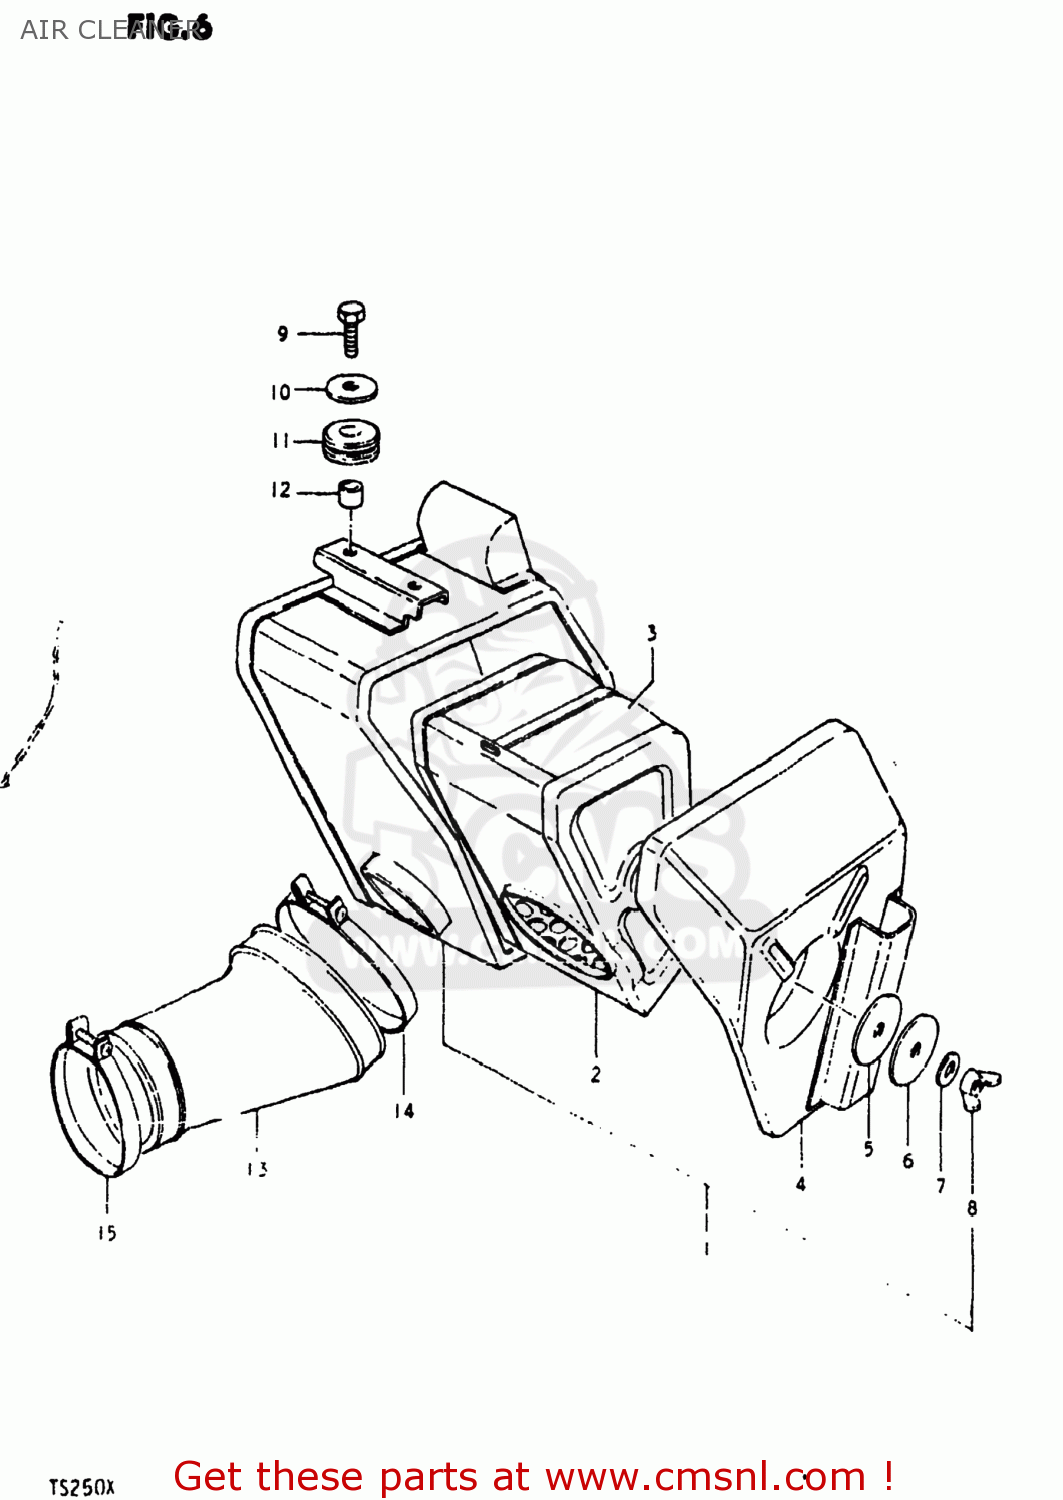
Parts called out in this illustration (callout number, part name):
1	CLEANER ASSEMBLY,AIR
2	FILTER ASSY
3	FILTER
4	CAP,AIR CLEANER
5	SEAL
6	WASHER,AIR CLEANER ELEMENT
7	WASHER
8	NUT
9	BOLT, UPPER
10	WASHER (6.5X20X1.2)
11	CUSHION
12	SPACER (7X9X7)
13	TUBE,AIR CLEANER OUTLET
14	CLAMP
15	CLAMP
